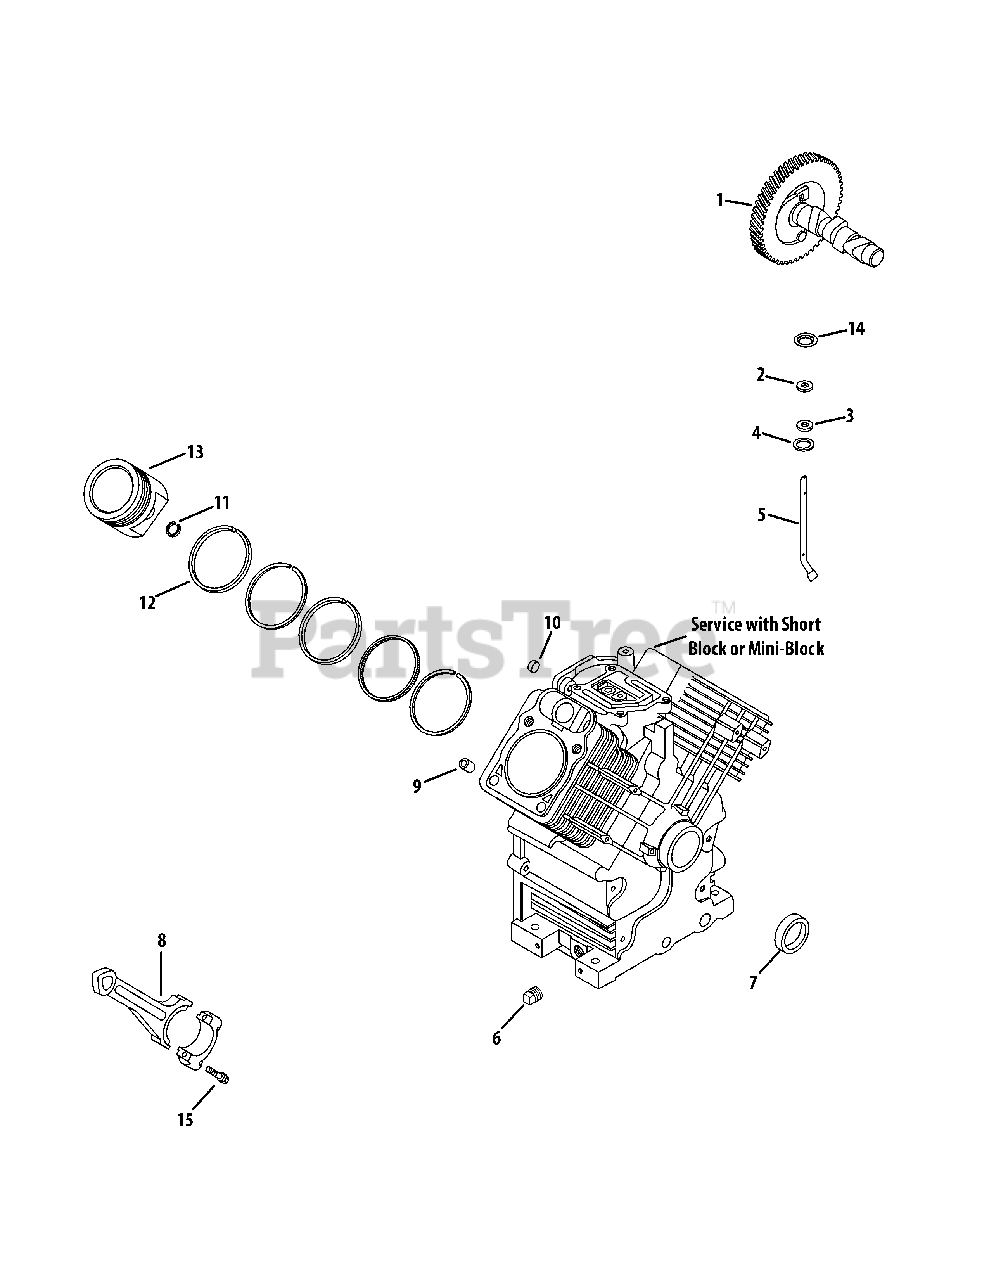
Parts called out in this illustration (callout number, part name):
1	Camshaft Kit
2	Flat Washer, 9 MM
3	Governor Cross Shaft Seal
4	Flat Washer, 11/32
5	Governor Cross Shaft
6	Square Headd Pipe Plug, 3/8
7	Oil Seal (Helix Lip)
8	Connecting Rod Assembly
11	Piston Pin Retainer
12	Ring Set (Std)
12	Ring Set (.08)
12	Ring Set (.25)
12	Ring Set (.50)
13	Piston Assembly Kit w/ Ring (Std.)
13	Piston Assembly Kit w/ Ring Set (.08)
13	Piston Assembly Kit w/Ring Set (.25)
13	Piston Assembly Kit w/ Ring Set (.50)
14	Ring Retainer
15	Rod Bolts Kit
